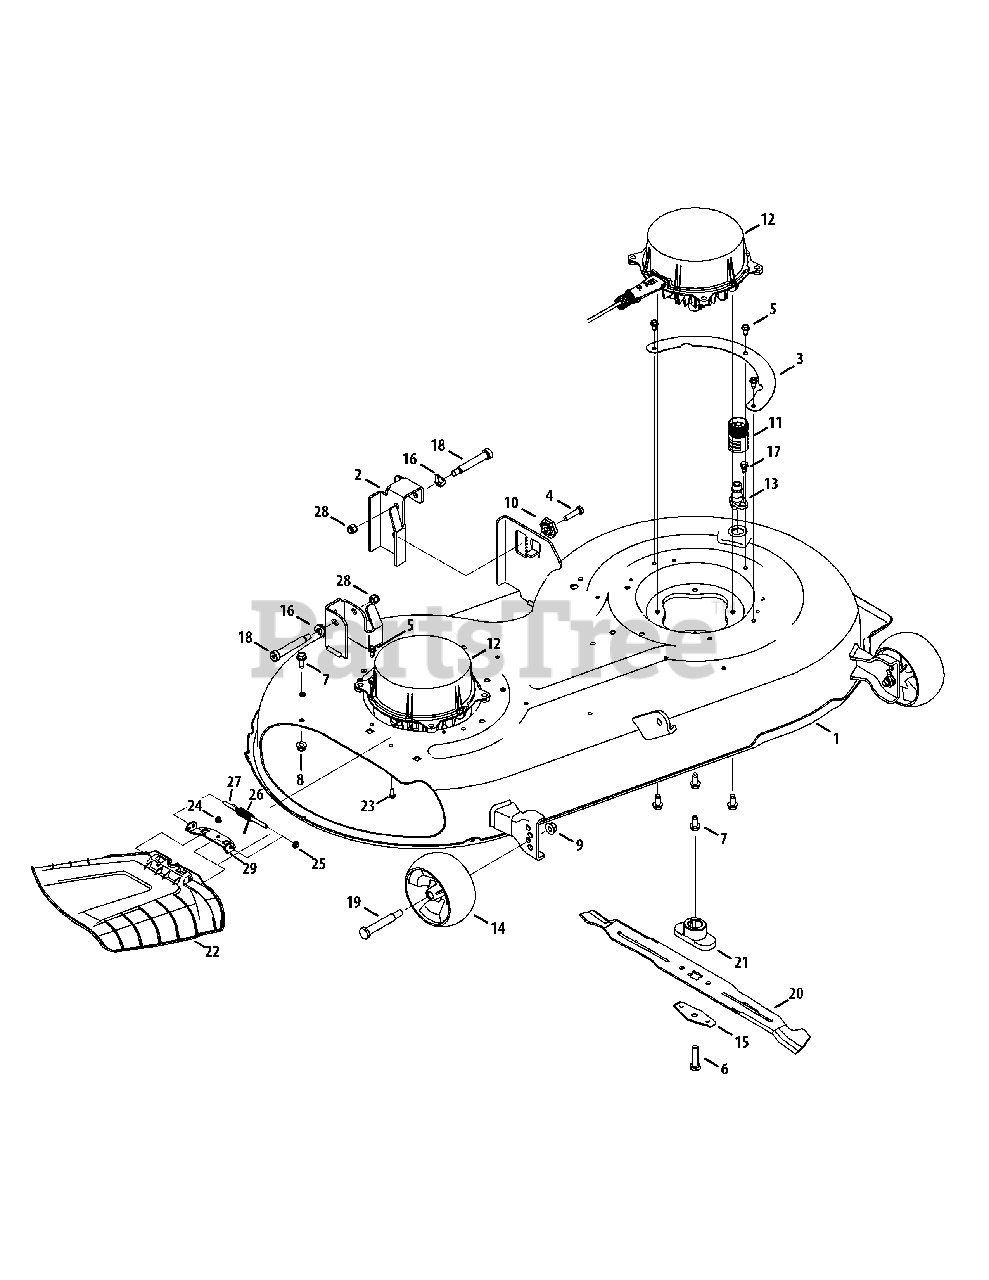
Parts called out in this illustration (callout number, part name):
4	Hex Cap Screw, 5/16-18 x 1.25
5	Hex Washer Screw, 1/4-20 x .500
6	Hex Cap Screw 3/8-24 x 1.50
7	Hex Washer Head Screw, 5/16-18 x .75
8	Flange Lock Nut, 5/16-18
9	Flange Lock Nut, 3/8-16
10	Deck Adjustment Gear
11	Water Nozzle Adapter
12	Deck Motor, 48V
13	Deck Wash Nozzle
14	Deck Ball Wheel, 5.0
15	Bell Blade Spacer
16	Spring Washer,.50 x 1.0 x.022
17	Shoulder Screw, .500 x 1/4-20
18	Shoulder Screw, .5 x 2.75 x 3/8-16
19	Shoulder Screw, .5 x 2.5 x 3/8-16
20	Blade, 21.18"
21	Blade Adapter
22	Chute Deflector Assembly
23	Hex Cap Screw, 1/4-20 x .62
24	Nut, Flange Lock, 1/4-20, Nylon
25	Push Cap
26	Spring, Torsion, .440 ID x 1.75
28	Hex Lock Nut, 3/8-16
